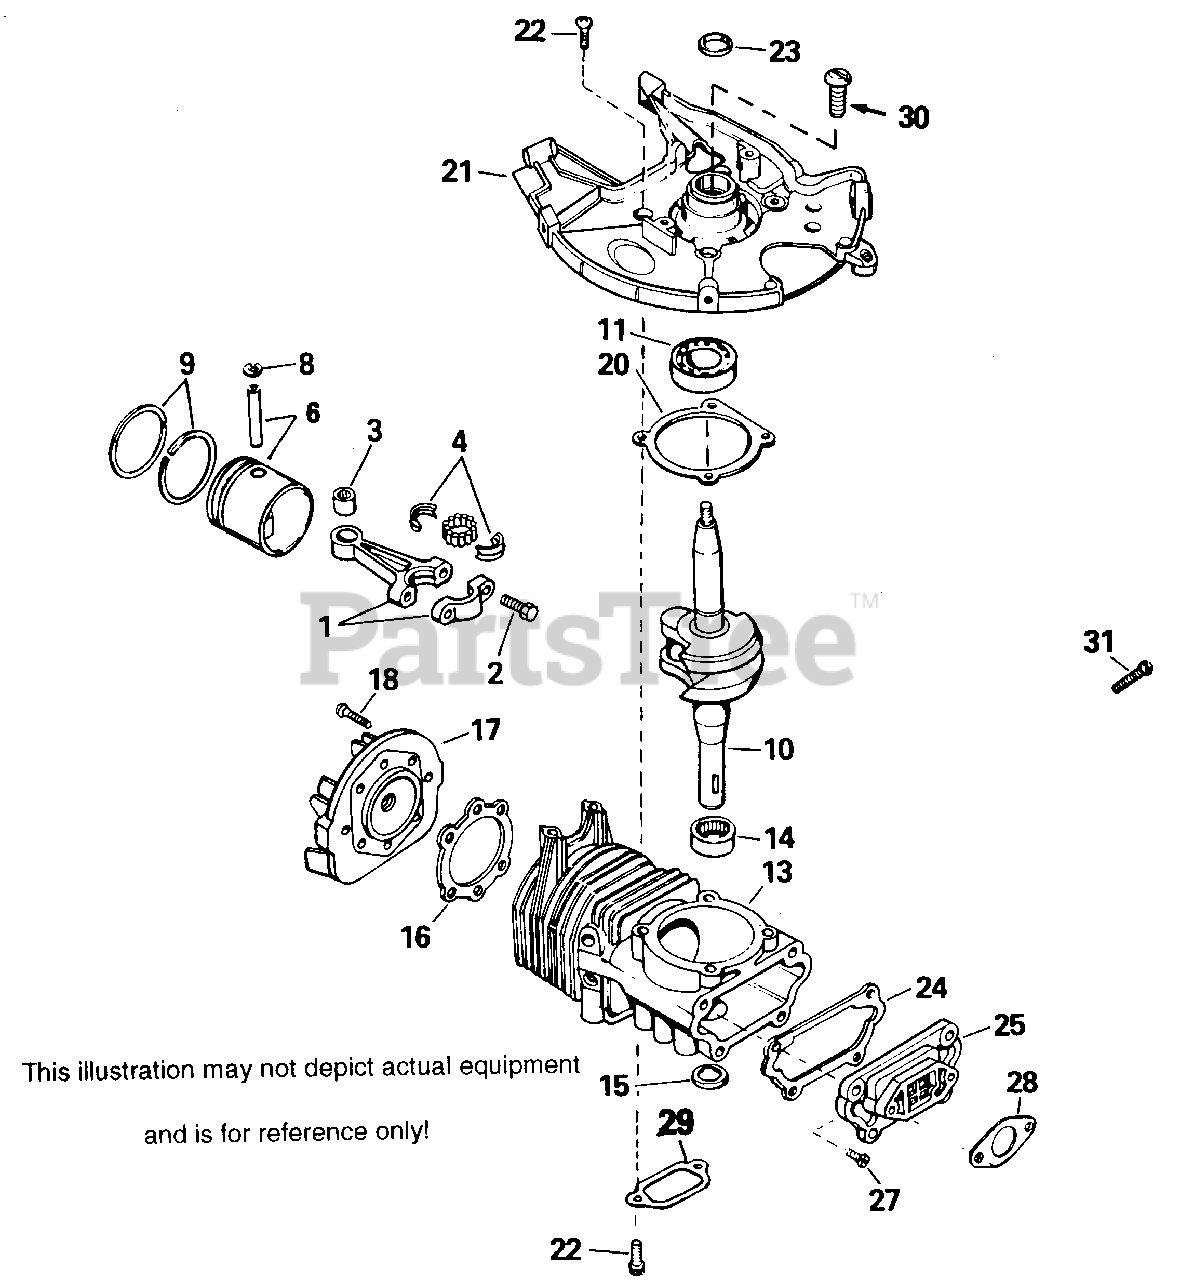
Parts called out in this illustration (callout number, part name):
1	"Rod Assy., Connecting Incl. 2, 3 & 4
2	Screw, Connecting rod
3	Bearing, Cartridge
4	Bearing & Liner Set, Needle
6	Piston & Pin Assy. (Incl. 8)
8	Ring, Piston pin retaining
9	Ring Set, Piston
10	Crankshaft
11	Bearing, Cartridge
13	Cylinder Order SB if replacement isre q.
14	Bearing, Cartridge
15	Oil Seal
16	Gasket, Cylinder head
17	CYL HEAD
18	Screw, Torx T-30, 1/4-20 x 3/4"
20	Gasket, Housing base
21	Housing Base (Incl. 11 & 23)
22	Screw, Torx T-30, 1/4-20 x 5/8"
23	Seal, Crankshaft
24	Gasket, Reed plate
25	Plate Assy., Reed
27	Screw, Torx T-25, 10-24 x 1/2"
28	Gasket, Carburetor
29	Gasket, Exhaust
